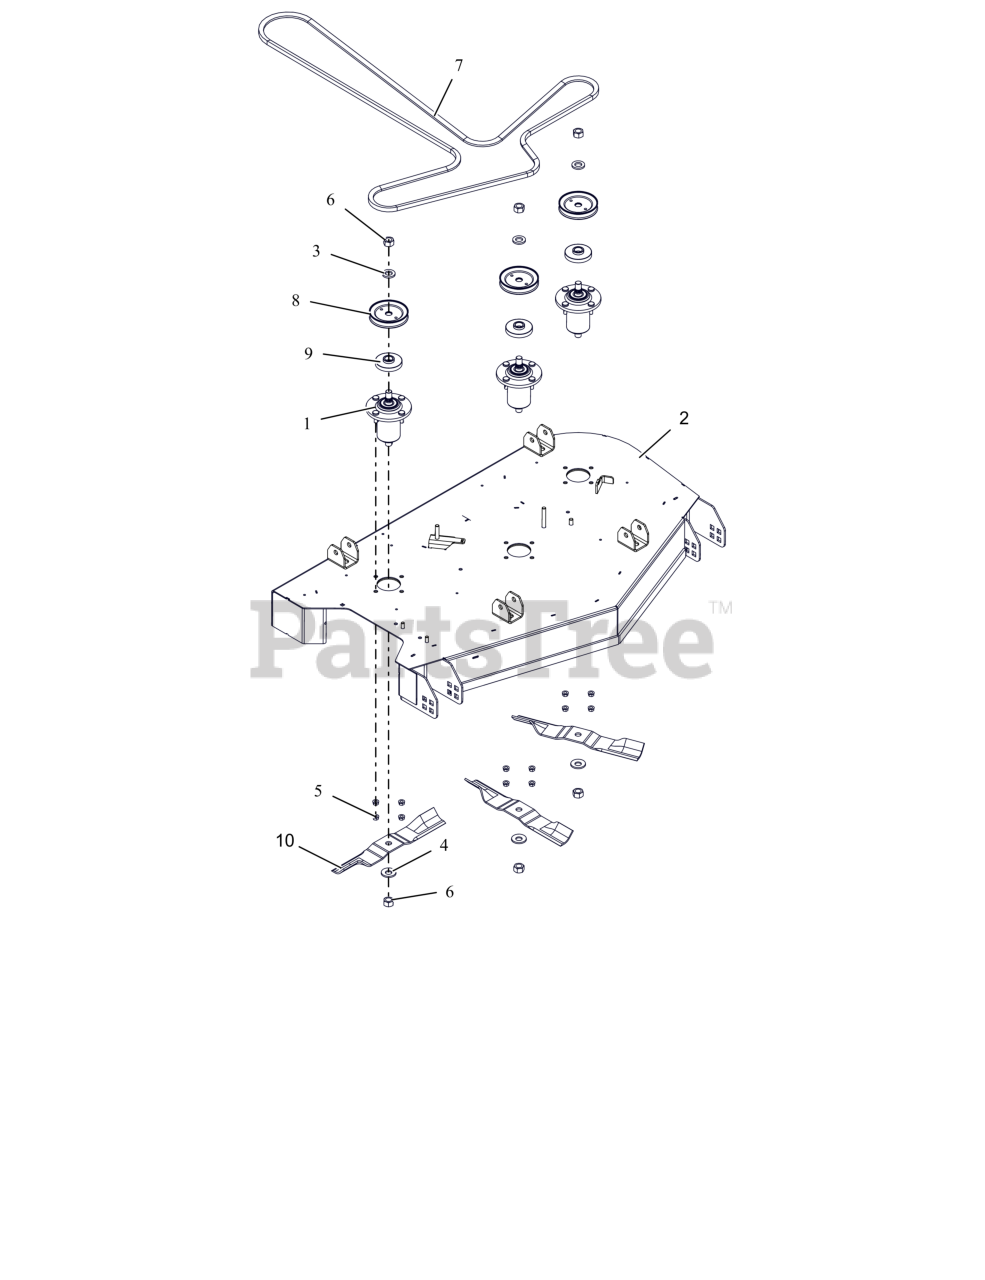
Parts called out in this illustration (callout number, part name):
1	ASM, ALUMINUM SPINDLE SUB
2	KIT,ARIENS DECK 42" WITH DECALS
4	WSHR-BLVL .669X1.535X.138
5	NUT,LK-CTR-FLG .31-18 GF ZCC
6	NUT-STD .625-18 ZCC
7	V-BELT, HA-WRAPPED
8	PULLEY, V-4.00 ODX.625 SPLINE ID
9	SHIELD, DUST
10	BLADE, MOWER 14.5"
